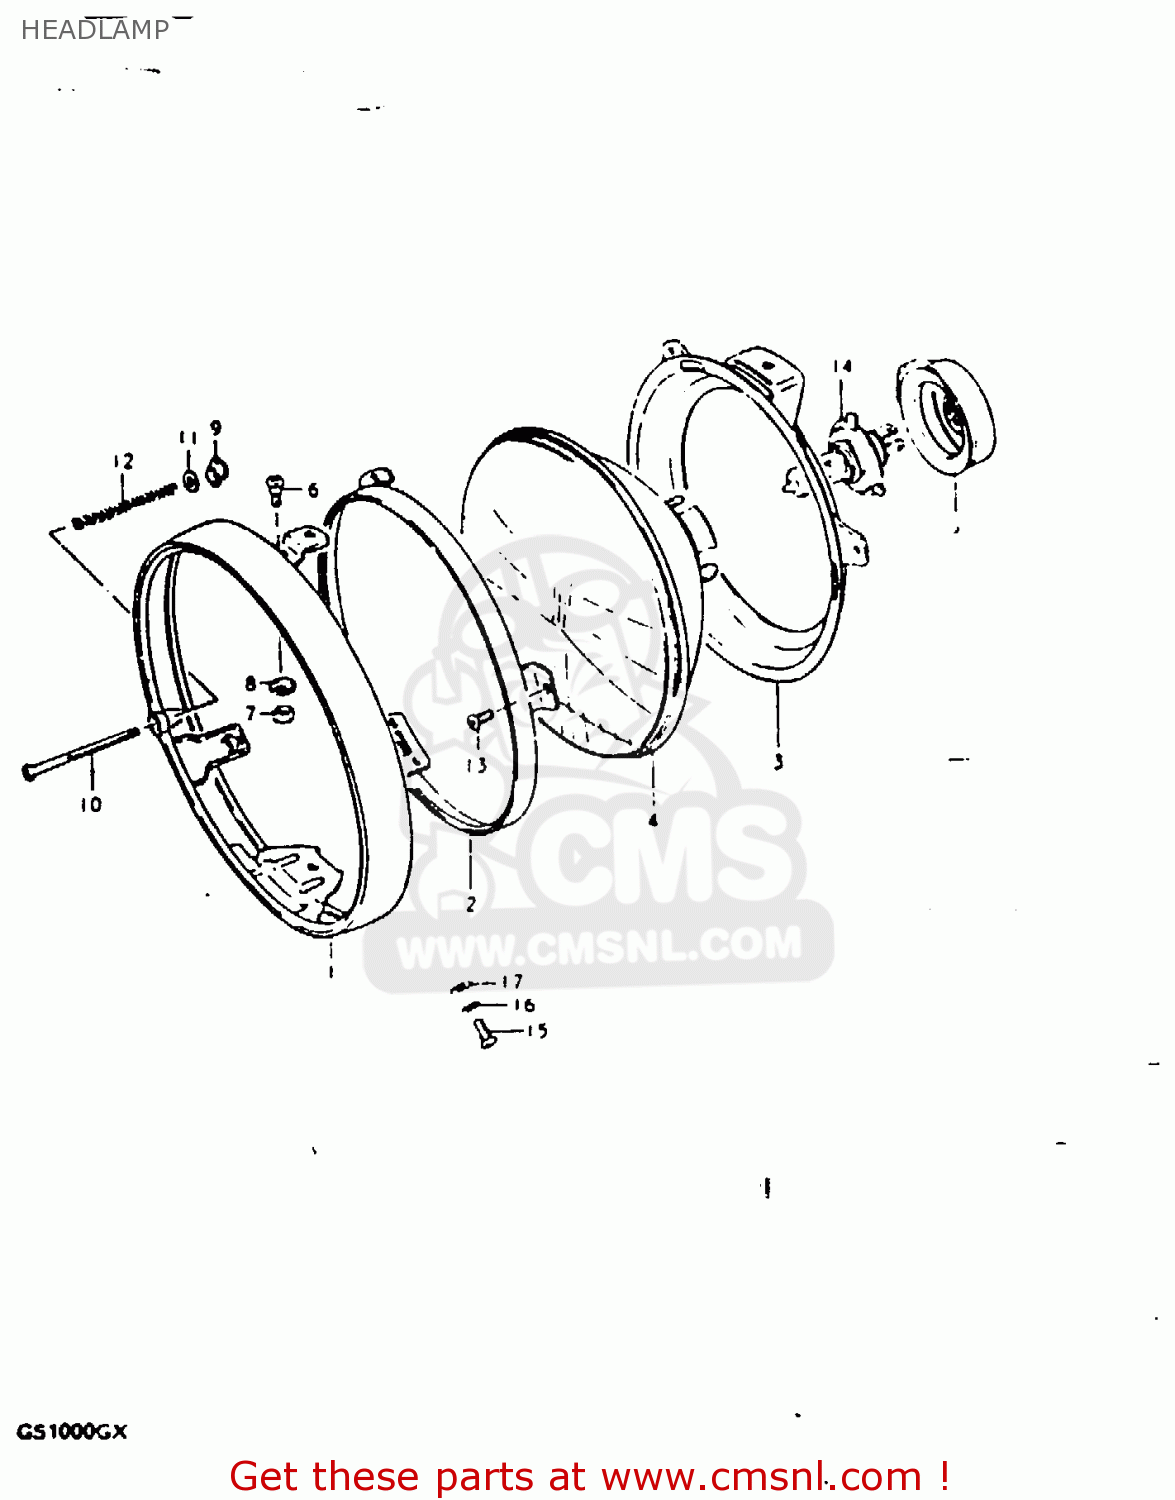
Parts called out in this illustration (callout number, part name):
1	RIM
2	RETAINER
3	RING,HEADLAMP UNIT
4	LAMP UNIT
5	COVER,HEADLAMP SOCKET
6	SCREW
7	NUT,ADJUSTING
8	SPACER
9	NUT
10	SCREW,HEADLAMP ADJUST
11	WASHER
12	SPRING,HEADLAMP ADJUST
13	SCREW
14	BULB(12V60/55W,H4)
15	SCREW
16	WASHER,LOCK
17	WASHER
